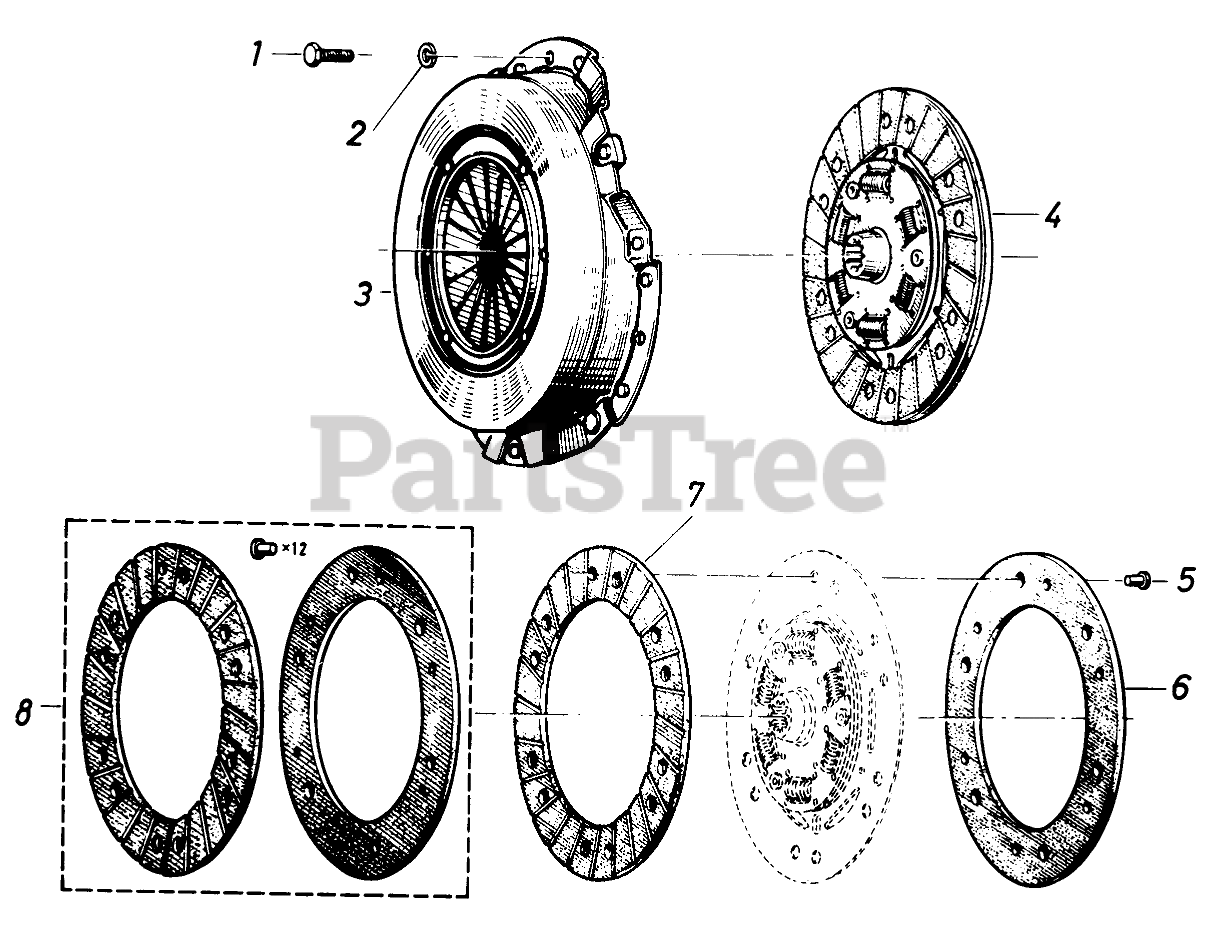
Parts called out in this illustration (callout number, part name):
1	Screw
2	Washer Spring
3	Clutch
4	CLUTCH PLATE
5	Rivet
6	Clutch Lining
7	Clutch Lining
8	CLUTCH LINING ASSY
